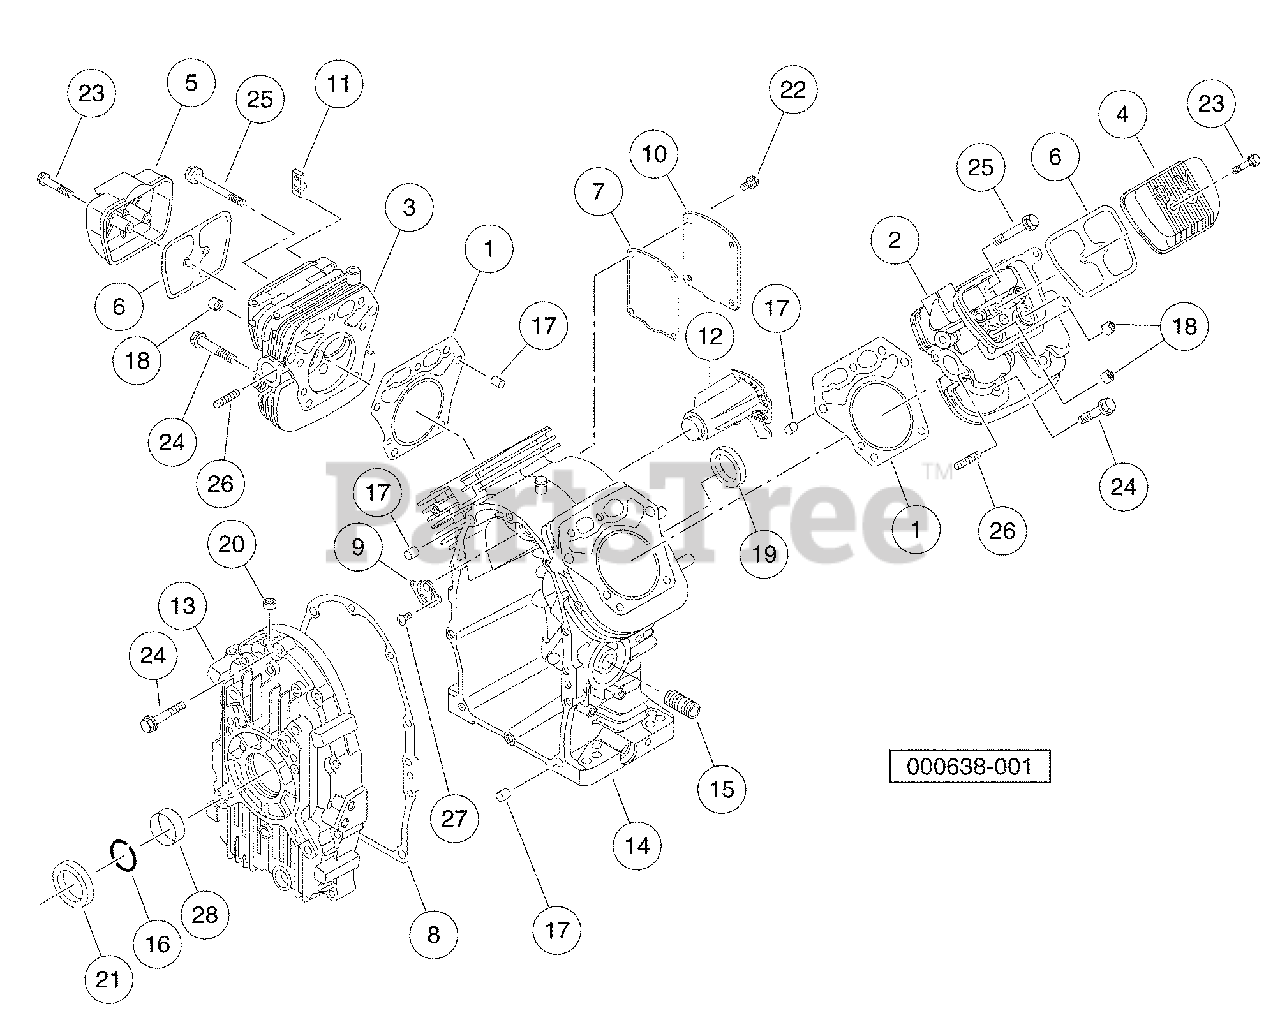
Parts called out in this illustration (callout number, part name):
1	Gasket, Head, Cyl, Fh
2	Head, Cyld 1, Fh
3	Head, Cyld 2, Fh
4	Cover, Rocker, Cyld 1, Fh
5	Cover, Rocker, Cyld 2, Fh
6	Gasket, Rocker, Cover, FH
7	Gasket, Breather, Fh
8	Gasket, Cover, Crank, Fh
9	Valve, Assy, Reed, Fh
10	Cover, Crkcase, Comp, Fh
11	Pipe, Head, Comp, Clyd, Fh
12	Pipe, Crkcase, Comp, Fh
13	Cover, Crankcase, Fh
14	Crankcase, Comp, Fh
15	Nipple, Oil Filter, Fh
16	Ring, Snap, Fh
17	Pin, Head, Fh
18	Seal, Oil, Valve, Fh
19	Seal, Oil, Crank, Rear, Fh
20	Seal, Oil, Governor, Fh
21	Seal, Oil, Crank, Front, Fh
22	Bolt, Flg, M6 X 1.0 X 12
23	Bolt, Flg, M6 X 1.0 X 40
24	Bolt, Flg, M8 X 1.25 X 50
25	Bolt, Flg, M8 X 1.25 X 75
26	Stud, M8 X 1.25, Exhaust, Fh
27	Screw, Pan, Governor, Fh
28	Bushing, Main, Fh
